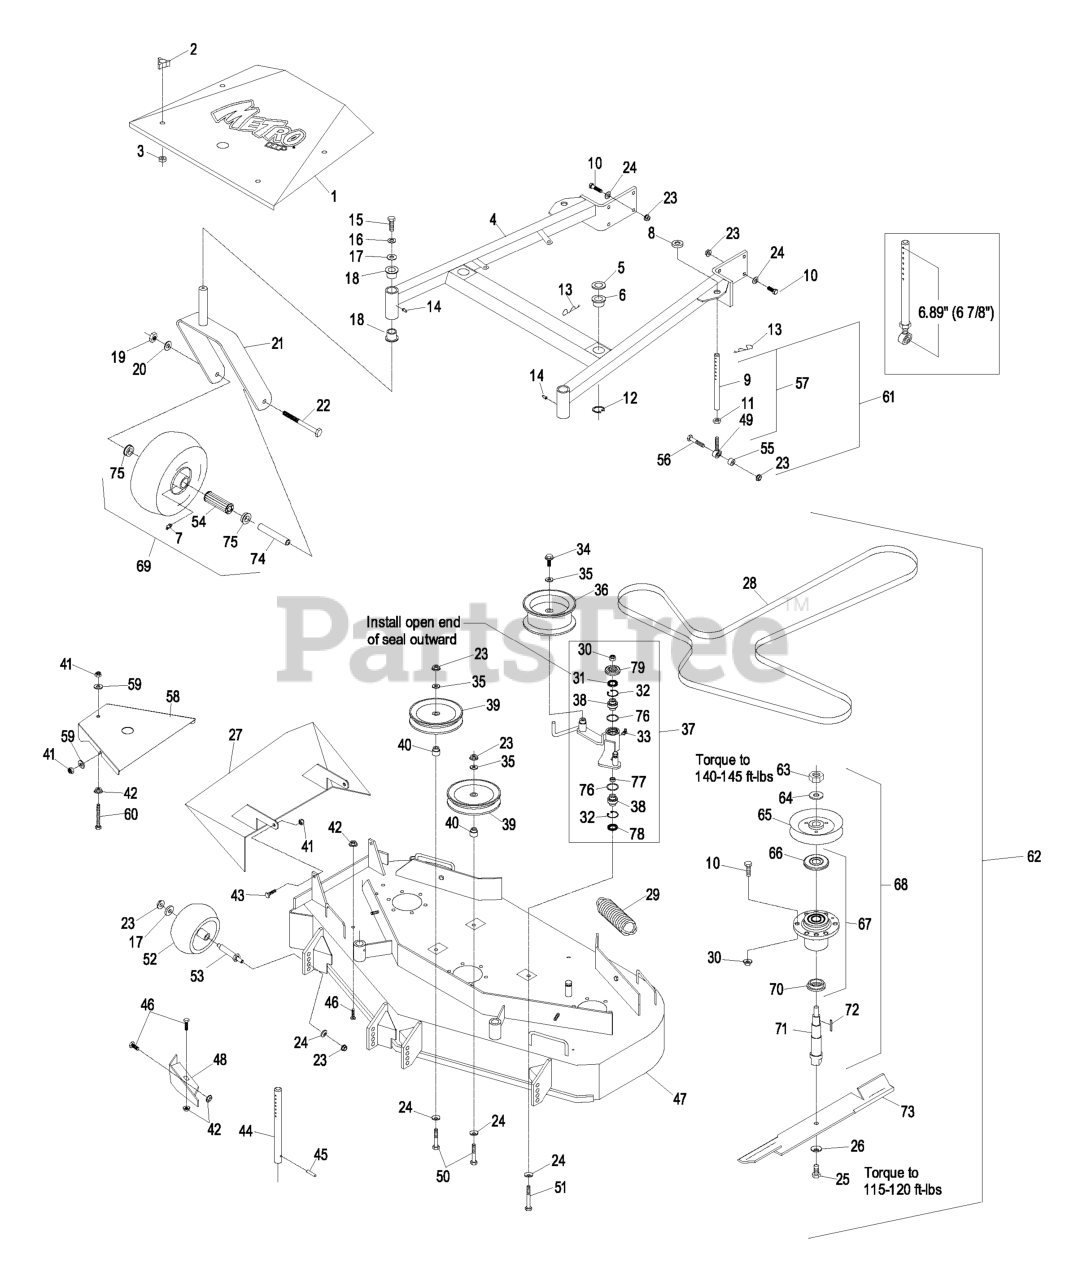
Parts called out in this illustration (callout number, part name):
1	SHIELD W/DECAL,MHP48
2	KNOB-3 PRONG
4	DECK SUPPORT W/BSHGS 48"
5	SPACER-DECK SUPPORT
6	BUSHING-DECK
7	FITTING-GREASE
9	LINK,SUPPORT
10	SCREW-HH
11	NUT-HEX
12	RING-RETAINING
13	PIN,HAIR COTTER
14	FITTING-GREASE
15	SCREW-HH
16	WASHER-LOCK
18	BEARING-FLANGED
19	NUT-HH
20	WASHER-LOCK
22	SCREW-HH
23	NUT-HHF, WHIZ
24	WASHER-BELLEVILLE
25	SCREW-CAP
26	WASHER-SPRING
27	WLD,DISCHARGE CHUTE 36/48
28	BELT - V, B
30	NUT-LOCK, NI
31	SEAL-LIP, SINGLE
32	RING-SNAP
33	FITTING-GREASE, 90 DEG
34	SCREW-HHF
35	WASHER-FLAT
37	KIT, DECK IDLER TTHP48&52
38	BEARING-SPHERICAL
39	PULLEY-IDLER
40	BUSHING-IDLER
41	NUT-LOCK, NI
43	SCREW-HH
44	ROD,DECK SUPPORT
46	SCREW-HH
47	ASM,DECK W/DECALS TTHP/MH
49	BALLJOINT
50	SCREW-HH
51	SCREW-HH
52	ROLLER-SCALP, ANTI
54	BEARING
56	SCREW-HH
58	SHIELD,BELT
59	WASHER-FLAT
60	BOLT,TAP HH
62	Asm, Deck Complete
63	NUT-HH
65	SHEAVE,W/HUB 5.72
66	GUARD-BEARING, TOP
67	KIT, CUTTER HOUSING
68	ASM, CUTTER HSG
69	KIT, SP CASTER WHEEL REPL
70	SPACER-GUARD, BOTTOM
71	SPINDLE,SHAFT
72	KEY-RECTANGLE
75	BUSHING
78	SEAL-LIP, DOUBLE
79	GUARD-TOP
